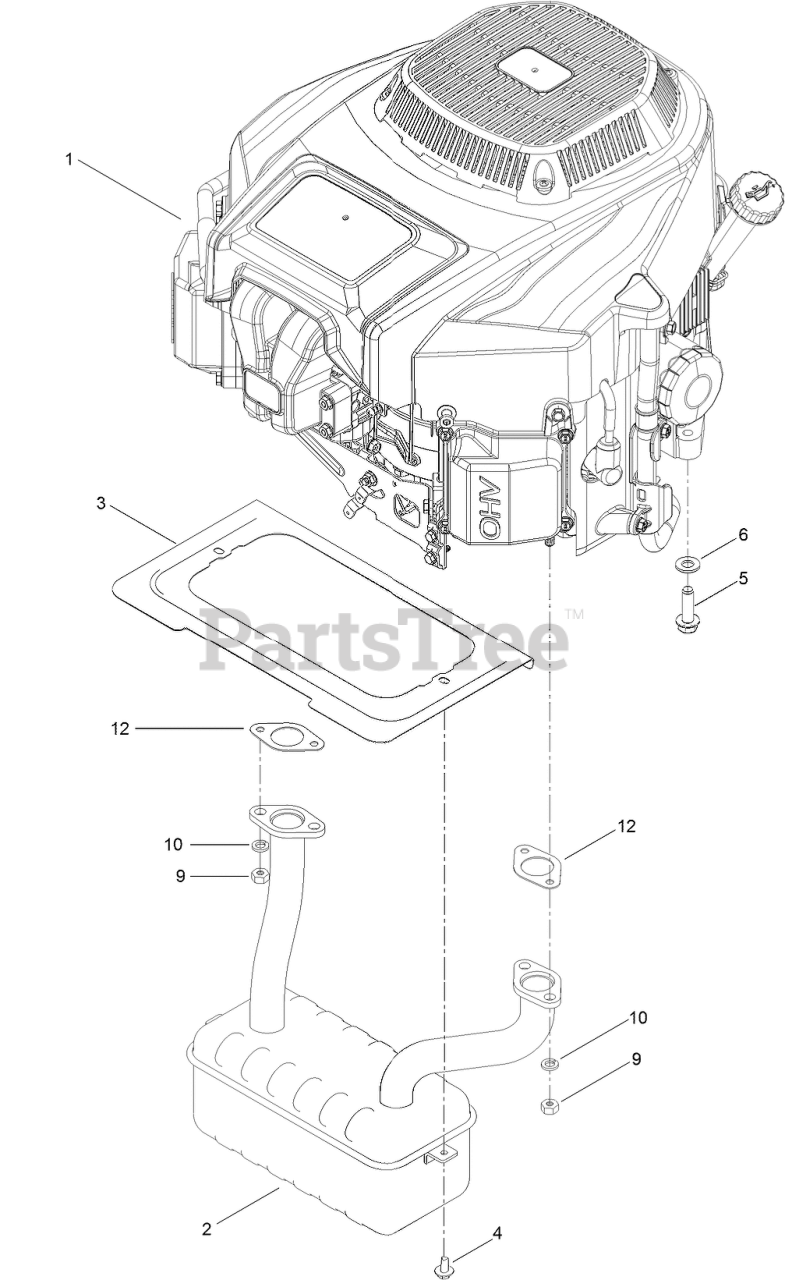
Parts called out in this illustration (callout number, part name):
1	ENGINE-2P77F
2	MUFFLER
3	SHIELD-HEAT
4	SCREW-HWH, THD ROLL
5	SCREW-HWH, THD ROLL
6	WASHER-FLAT
9	NUT-HH
10	WASHER-LOCK, SPLIT
12	GASKET-EXHAUST
